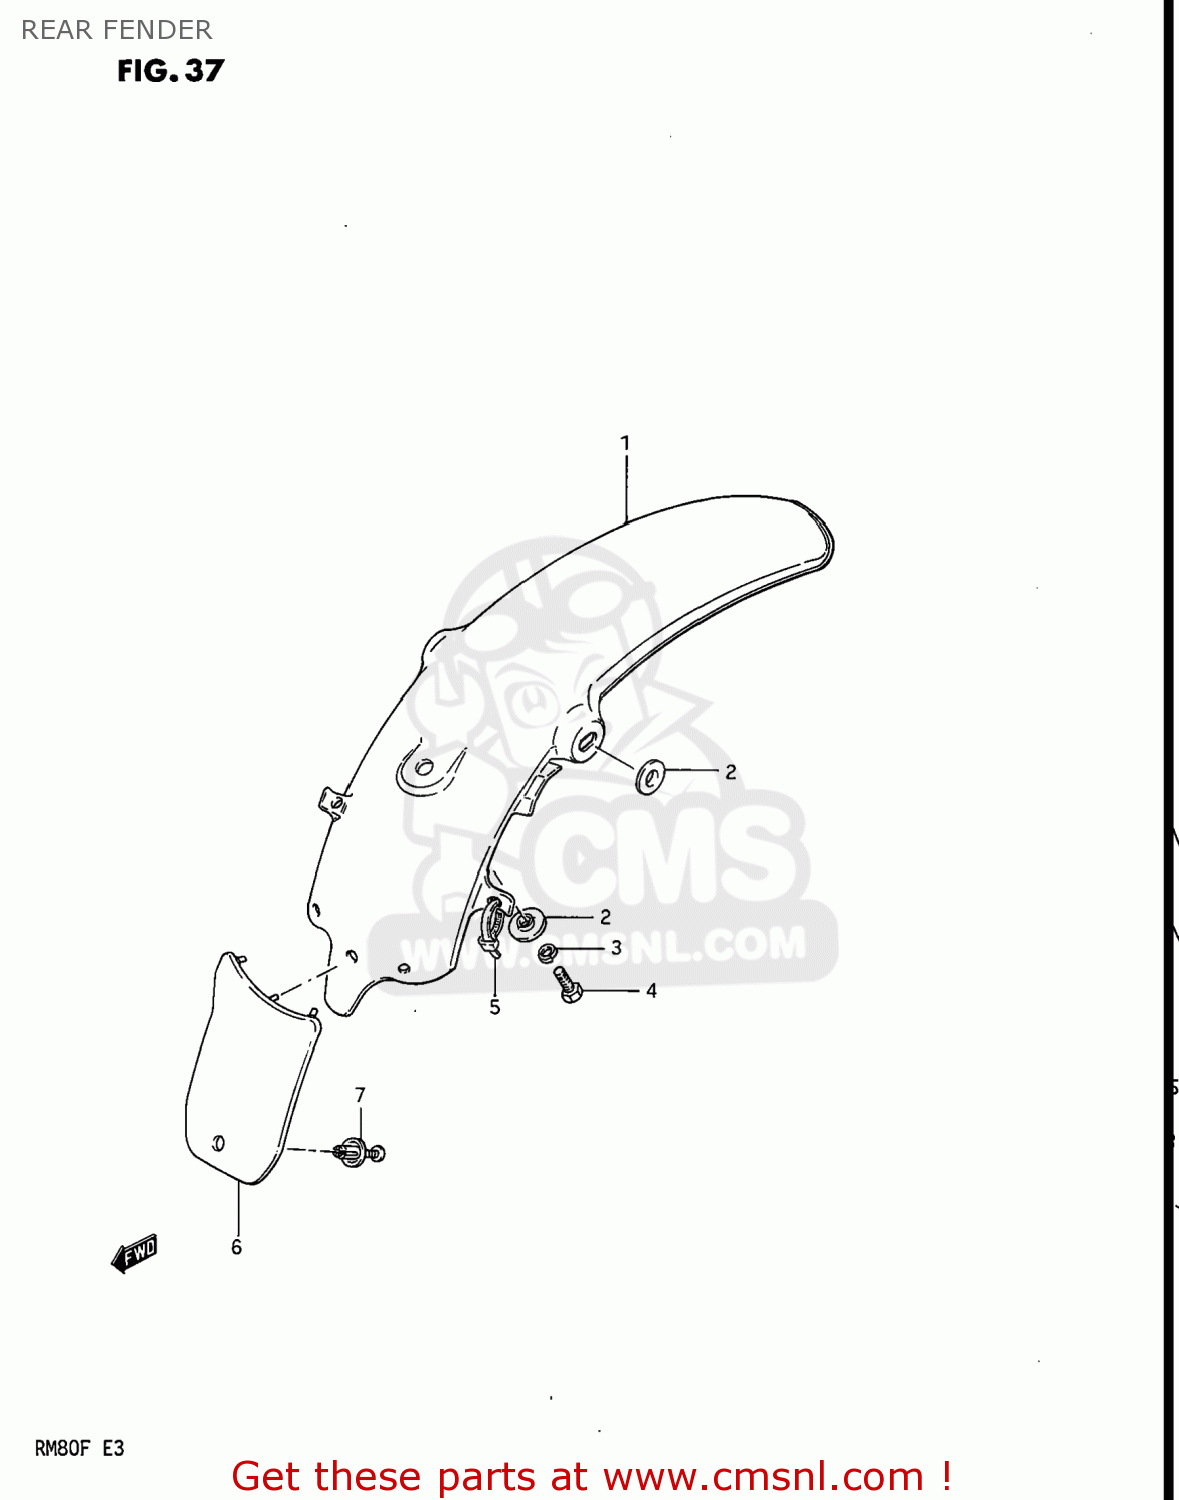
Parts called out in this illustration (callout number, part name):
1	FENDER,RR
2	WASHER
3	LOCK WASHER
4	BOLT, UPPER
5	CLAMP
6	GUARD,MUD
7	CLIP
